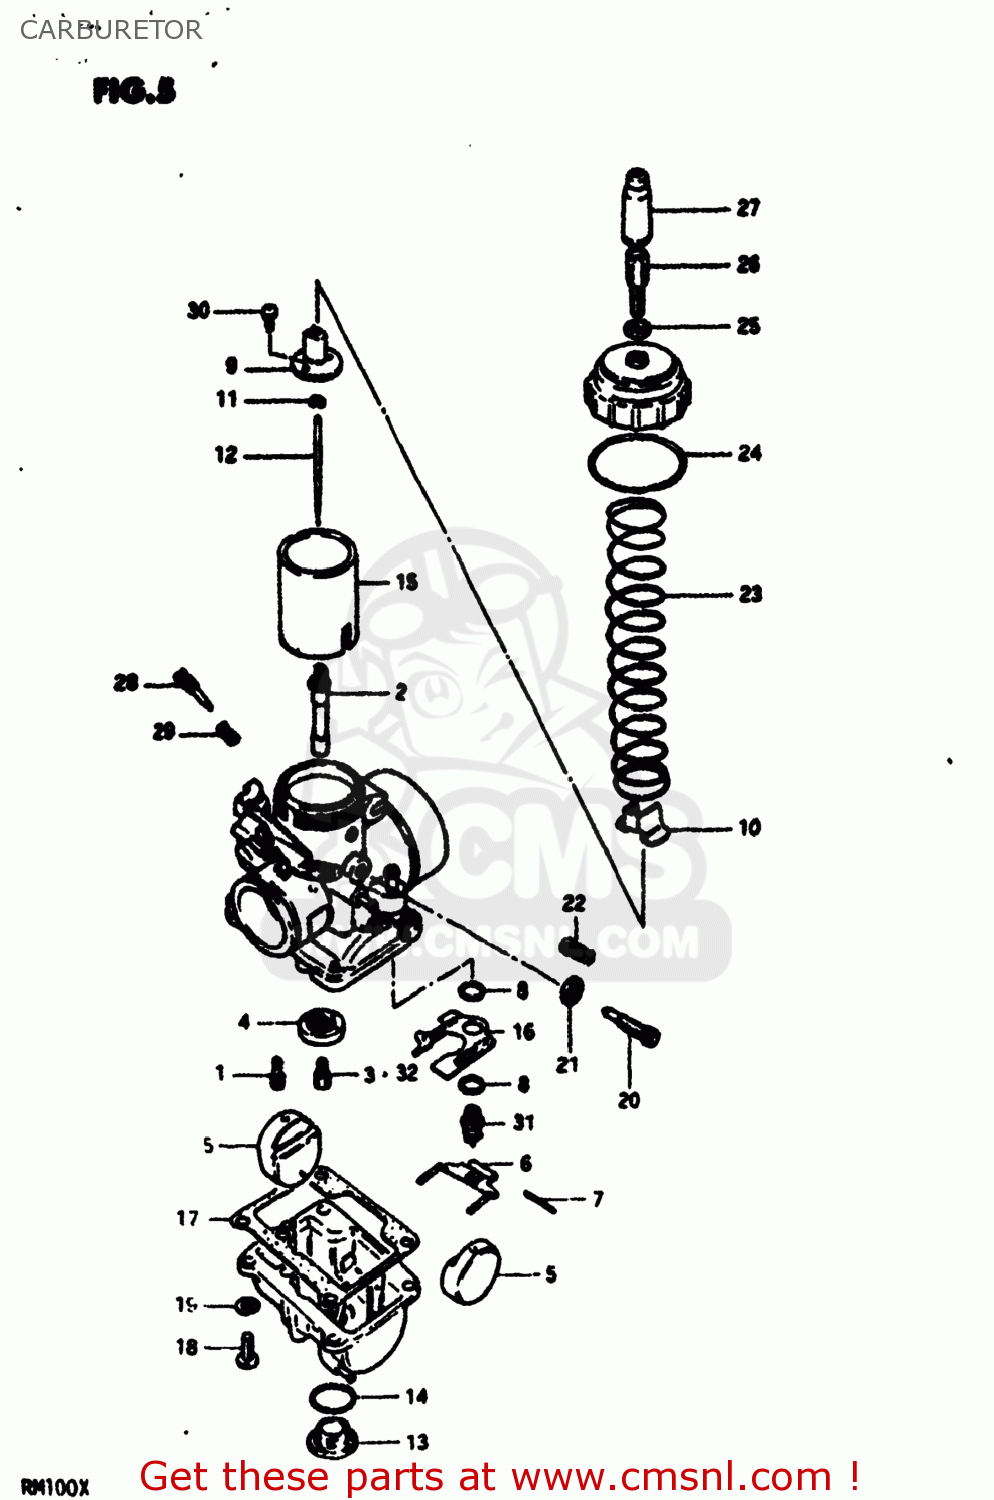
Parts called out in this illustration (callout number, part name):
0	CARBURETOR ASSEMBLY
1	JET
2	JET,NEEDLE
3	JET
4	RING,MAIN JET FIXING
5	FLOAT
6	ARM,FLOAT
7	PIN,FLOAT
8	GASKET,MAIN JET HOLDER (NAS)
9	CONNECTOR
10	COVER,HOLDER
11	CLIP
12	NEEDLE JET
13	PLUG
14	GASKET,DRAIN PLUG
15	VALVE,THROTTLE
16	PLATE
17	GASKET,FLOAT CAHMBER (NAS)
18	SCREW
19	LOCK WASHER
20	ADJUSTER
21	NUT
22	SPRING,THROTTLE SCREW
23	SPRING,THROTTLE VALVE RETURN
24	O-RING,MIXING CHAMBER
25	NUT
26	ADJUSTER,CABLE
27	CAP
28	SCREW,PILOT AIR
29	SPRING
30	SCREW
31	VALVE ASSY,NEEDLE
32	JET
